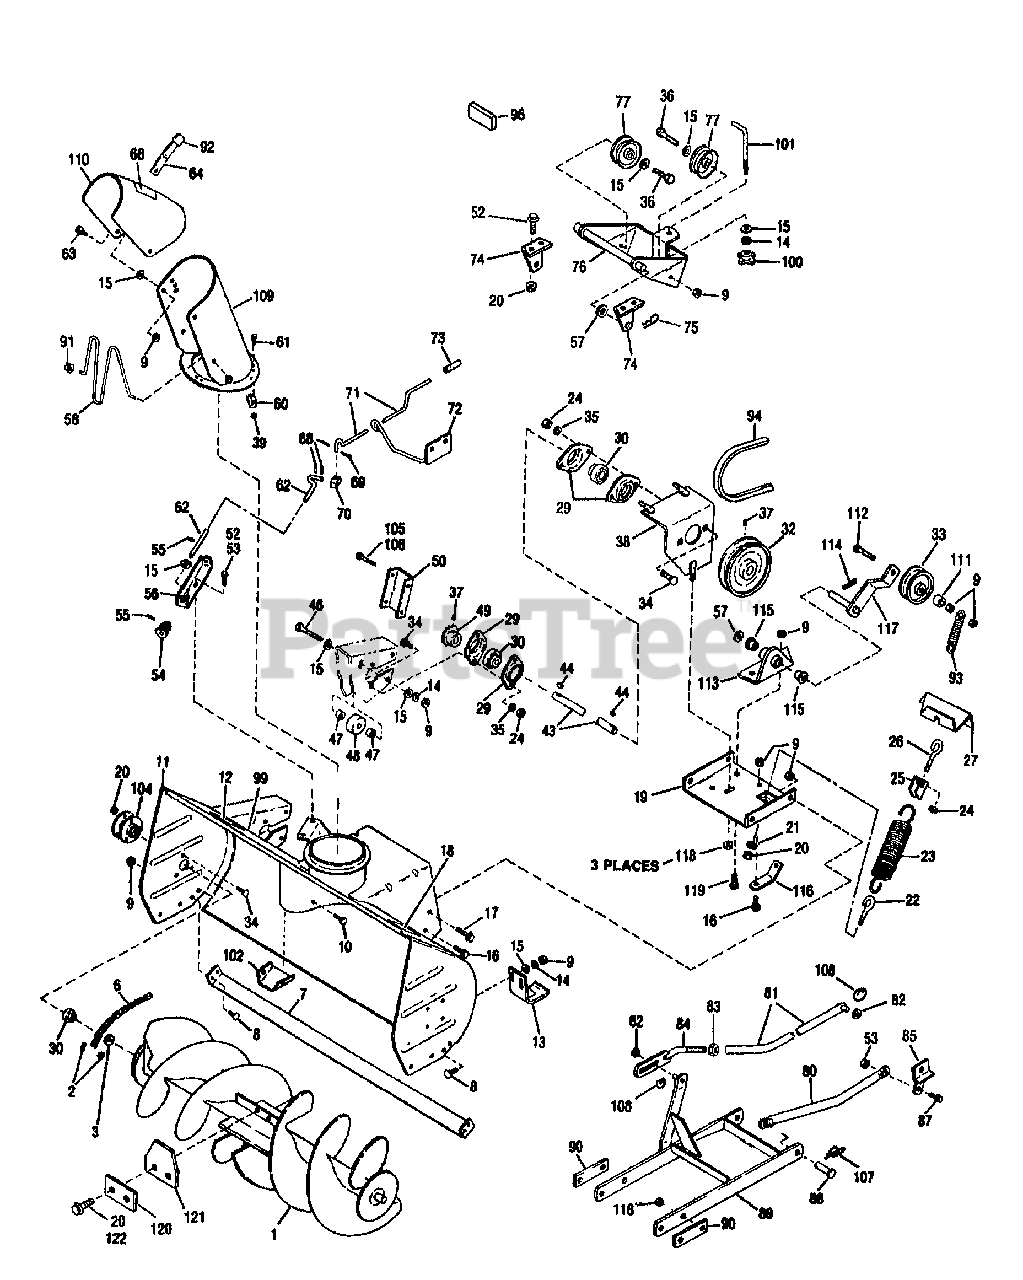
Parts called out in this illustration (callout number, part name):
1	ASSM-ROTOR 38"
2	LINK-CONNECTOR
3	WASHER-THRUST 1.1X.76X.05
6	CHAIN-DRIVE
7	SCRAPER
8	SCR-CARR 3/8-16X1.00
9	NUT-LOCK 3/8-16
10	SCR-HH 3/8-16X.50
11	ASSM-ROTOR HOUSING
12	DECAL-LOGO
13	SHOE-SKID
14	WASHER-LK .375 @ DEPL
15	WASHER-FLAT 3/8 SAE
17	SCR-HFLK 3/8-16X1.25 ZP
18	DECAL-WARNING
20	NUT-TOP/LK 5/16-18 ZP
21	WASHER-FLAT 5/16 SAE
23	SPRING-EXTENSION
24	NUT-HEX 5/16-18 ZP
25	BRKT-SPRING
27	BRKT-ANCHOR SPRING
29	BEARING-FLANGE
30	BEARING-BALL
32	SHEAVE-DRIVE
34	SCR-CARR 5/16-18X.75 G2 ZP
35	WASHER-LK .312 ZP
36	SCR-HH 3/8-16X1.75 G5 ZP
37	SCR-SET
38	ASSM-BRACKET
39	NUT-H/LK M10-24 NYLOCK
43	ROTOR DRIVE SHAFT
44	KEY-WOODRUFF .188X.75
46	SCR-HH 3/8-16X3.0 G5 ZP
47	SPACER-.68X.39X.46
48	BLOCK-TENSION
52	SCR-HFLK 5/16-18X.75 ZP
53	NUT-HFLK 5/16-18 ZP
54	GEAR-WORM LH
55	PIN-DRIVE .09X.75
56	SUPPORT-SHAFT
57	WASHER-1.305X.649X.098 ZP
58	GUARD-CHUTE
60	CLIP-HOLD DOWN
61	SCR-SEMS MACH
62	SHAFT-PINION
63	SCR-HH 3/8-16X.75 G5 ZP
64	LEVER-ADJUSTING
68	PIN-ROLL 1/8 X 3/4
69	PIN-COTTER .125 X .75 ZP
70	BLOCK-SWIVEL NYLON
71	CRANK-HANDLE
72	ASSM-CRANK SUPPORT
73	GRIP-PLASTIC
74	BRACKET-IDLER
75	PIN-HITCH .125X2.56 ZP
76	ARM-IDLER ADJUSTING
77	PULLEY-IDLER
80	ASSM-STRUT SUPPORT
81	ASSM-LIFT TUBE
82	WASHER-1.06X.531X.1 ZP
84	ASSM-LIFT ROD
85	ASSM-BRKT RH
87	SCR-LOCK
88	PIN-CLEVIS
89	ASSM-PUSH ARM
91	NUT-PUSH 3/16
92	GRIP-VACUCUT
94	BELT-V
96	REFLECTOR
99	DECAL-WARNING
101	ROD-ADJUSTOR
102	ASSM-DEFLECTOR
105	SCR-HH 1/4-20X3.0 G5 ZP
107	RING-COTTER
108	RING-CIRCLE COTTER
109	ASSM-DISCHARGE CHUTE
110	CAP-DEFLECTOR W/DECAL
112	SCR-HH 3/8-16X2.75 G5 ZP
113	ASSM-PIVOT SUPPORT
114	PIN-COTTER .120X1.00 ZP
115	BUSHING-.81X.62X.62 FLNG
116	ARM-SPRING ANCHOR
117	ASSM-IDLER ARM
118	NUT-HFLK 3/8-16 ZP
119	SCR-HH 3/8-16X1.0 G5 ZP
122	SCR-HFLK 5/16-18X1.25 ZP
